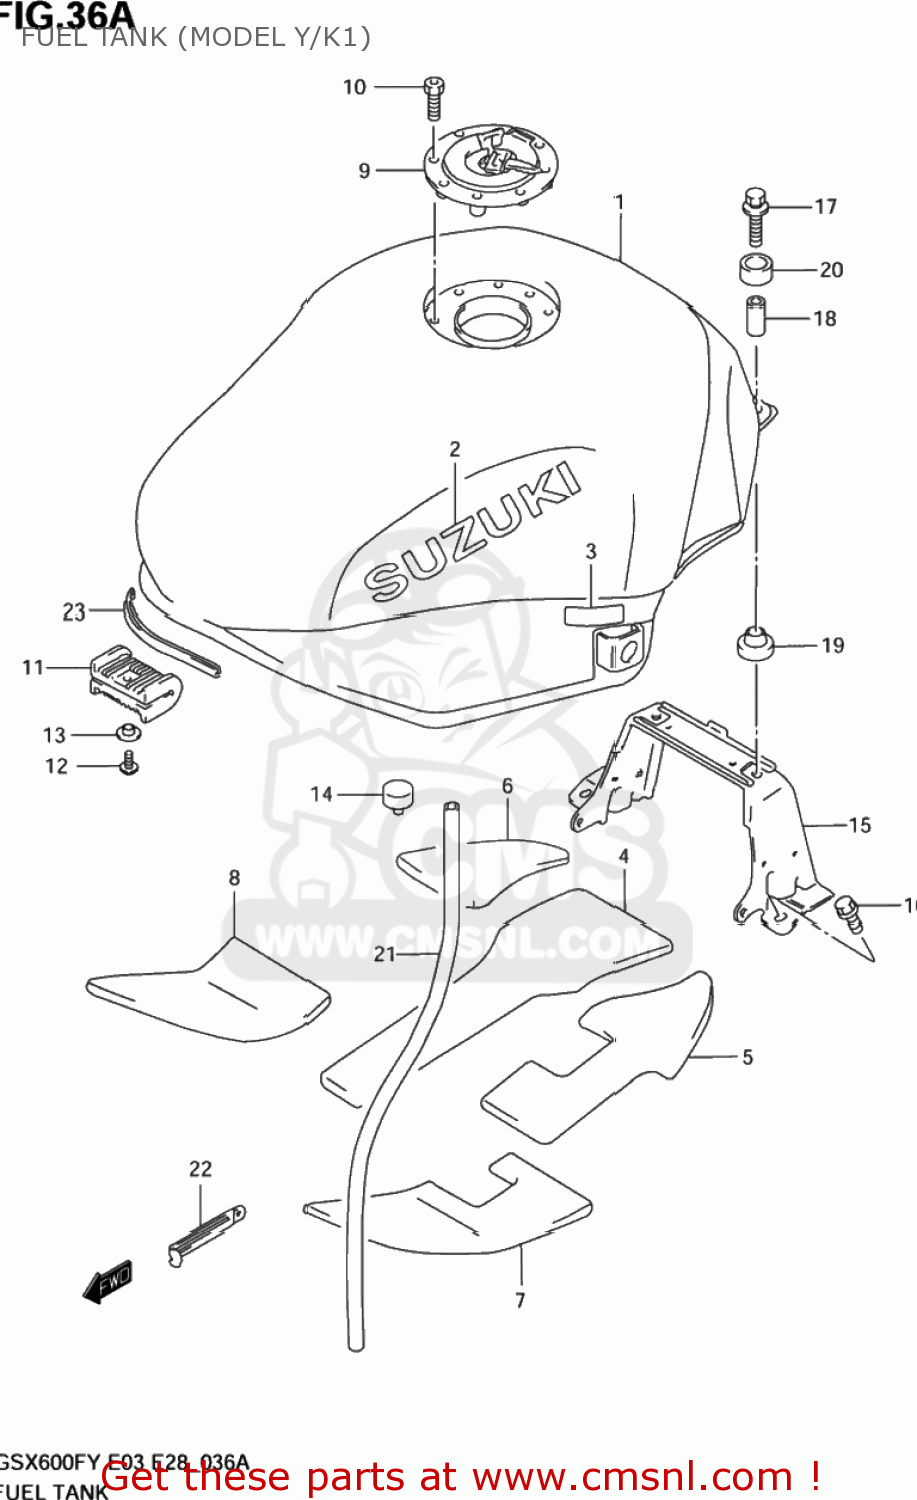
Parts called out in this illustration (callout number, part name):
1	TANK ASSEMBLY,FUEL
2	EMBLEM,FUEL TA
3	PROTECTOR(12X40)
4	SHIELD,FUEL TANK HEAT NO.1
5	SHIELD,FUEL TANK HEAT NO.2
6	SHIELD,FUEL TANK HEAT NO.3
7	SHIELD,FUEL TANK HEAT NO.4
8	SHIELD,FUEL TANK HEAT NO.5
9	CAP SET,FUEL TANK
10	BOLT(5X20)
11	CUSHION,FUEL TANK FR
12	SCREW 5X12
13	WASHER
14	CUSHION
15	BRACKET,FUEL TANK RR
16	BOLT
17	BOLT(6X30)
18	SPACER(6.5X9X18)
19	CUSHION
20	CUSHION
21	HOSE,FUEL TANK WATER DRAIN
22	CLAMP(L:120 T:1.0)
23	MOLDING,FUEL TANK
